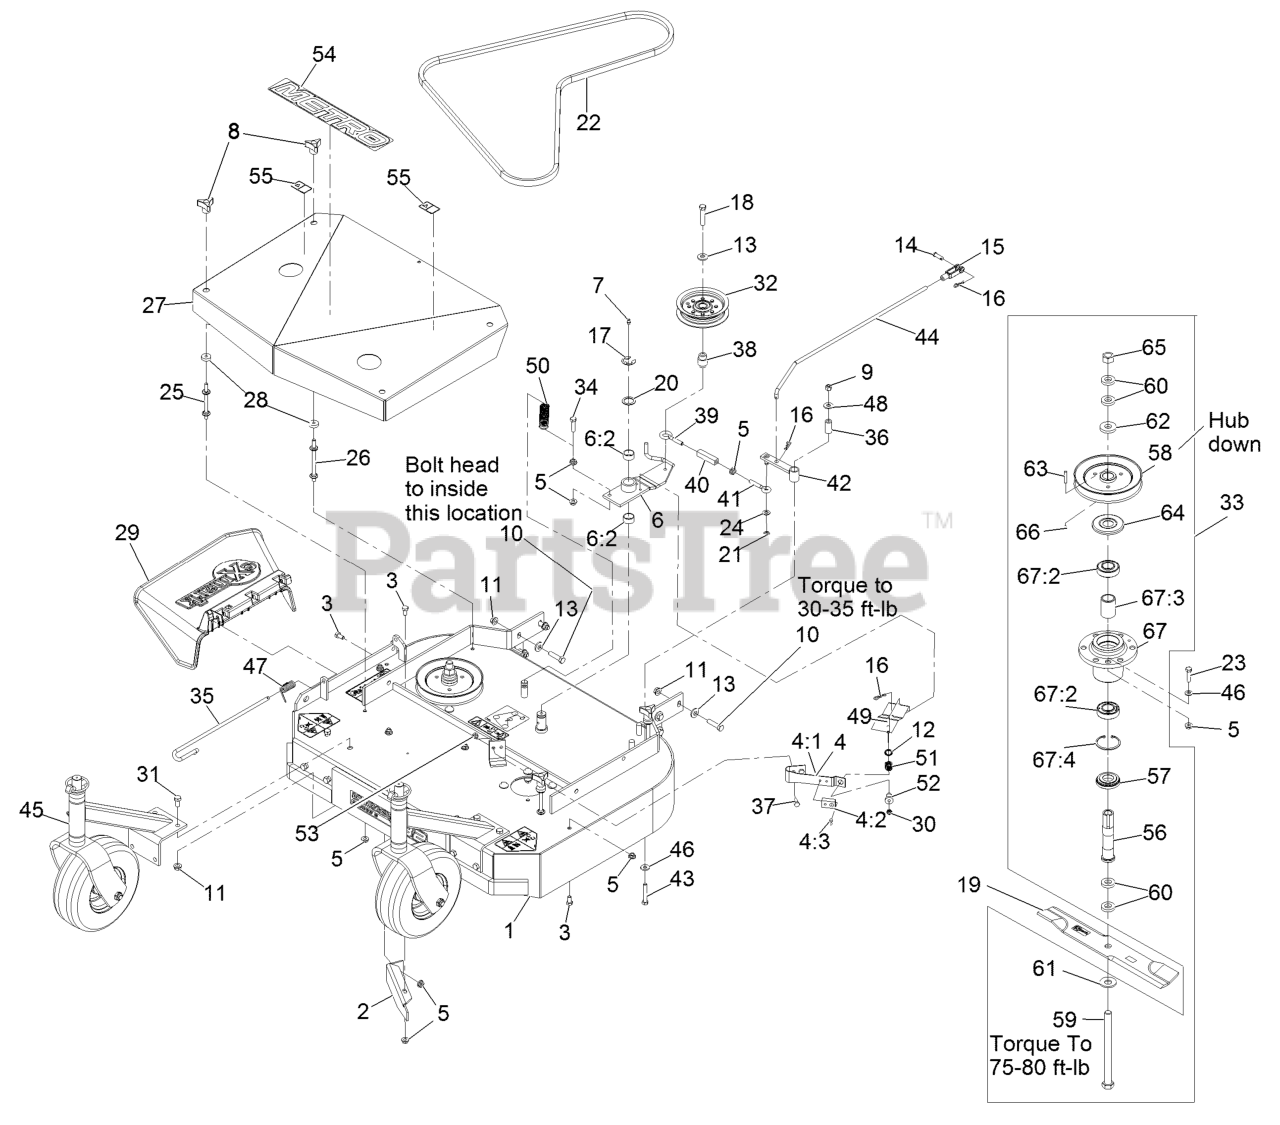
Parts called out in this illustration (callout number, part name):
1	ASM, DECK 32 RIGID
2	BAFFLE-DOGLEG
3	SCREW-HH
4	PAD AND SPRING ASM
4:1	PAD-BRAKE
4:3	RIVET-POP
6	IDLER ARM ASM
6:2	SLEEVE-BEARING
7	FITTING-GREASE
8	KNOB-3 PRONG
9	NUT-LOCK, NI
10	SCREW-HH
11	NUT-HHF, WHIZ
12	RING-PUSH ON
13	WASHER-BELLEVILLE
14	PIN-CLEVIS
15	YOKE-ADJUSTABLE
16	PIN-COTTER
17	RING-RETAINING, EXT
18	SCREW-HH
20	WASHER-SPINDLE
21	RING-RETAINING, EXT
22	BELT,BLADE METRO 32
23	SCREW-HH
24	WASHER-PLAIN
25	STUD-SHIELD, BELT (SHORT)
26	STUD-SHIELD, BELT (LONG)
27	ASM,SHIELD W/DECALS 32 ME
29	CHUTE DEFLECTOR XRK M056
30	NUT-LOCK, NI
31	SCREW-HH
33	ASM, CUTTER HOUSING OUTER
34	SCREW-HH, SPECIAL
35	PIN-CHUTE
36	TUBE-PIVOT
37	SCREW-HH
38	BUSHING-ENGAGEMENT
39	EYEBOLT-THREAD, LH
40	BODY-TURNBUCKLE
41	EYEBOLT-THREAD, RH
42	ARM-ASSIST, 32/36
43	SCREW-HH
44	ARM-ASSIST, LINKAGE
45	ASM,CASTER/MOUNT
46	WASHER-SPRING
47	SPRING, TORSION
48	WASHER-FLAT
49	ROD-BRAKE
50	SPRING-EXTENSION
51	SPRING-COMPRESSION
52	SPACER-FLANGED
53	NUT-LOCK, NI
54	Decal-Metro
55	DECAL-WARNING
56	TUBE-SPINDLE, SHORT
57	SPACER-GUARD, BOTTOM
58	SHEAVE
59	SCREW-CAP, HH
61	WASHER-SPRING
62	WASHER-RETAINER, SHEAVE
64	GUARD-BEARING, TOP
65	NUT-HEX
66	SETSCREW
67	KIT, CUTTER HOUSING
67	Cutter Housing ASM
67:2	BEARING-JACKSHAFT
67:3	SPACER-BEARING
67:4	RING-SNAP
